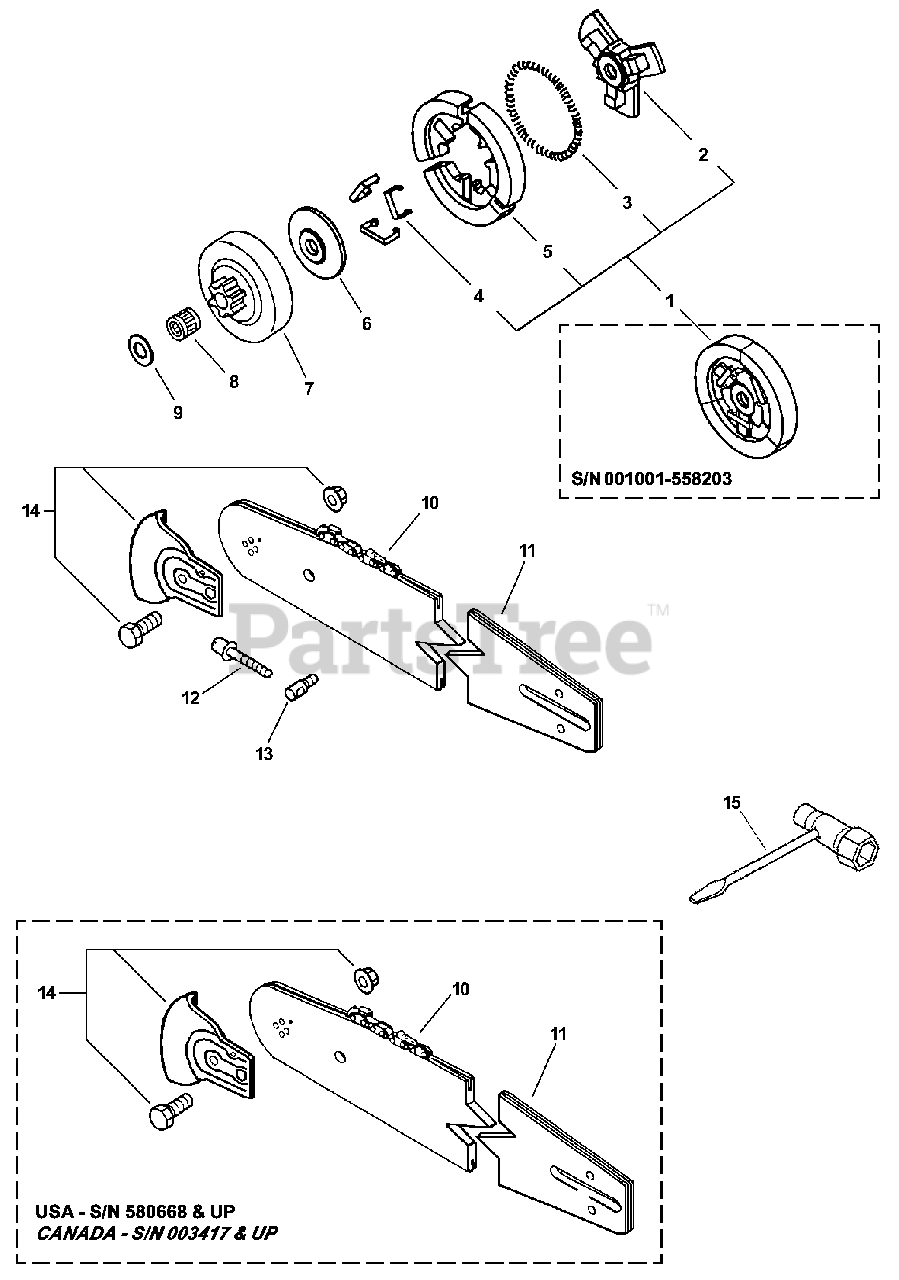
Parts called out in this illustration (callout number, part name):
1	CLUTCH ASSY
2	HUB, CLUTCH
3	SPRING, TORSION
4	SPRING, FLAT
5	SHOE, CLUTCH
5	SHOE SET, CLUTCH (3PCS)
6	PLATE, CLUTCH
7	DRUM, CLUTCH 3/8"
8	BEARING, NEEDLE 10×13×10
9	WASHER 10.2×24.5×1.2
10	SAWING CHAIN - 12" -- XTRAGUARD
10	SAW CHAIN 14" XTRAGUARD
10	SAW CHAIN 16"
11	GUIDE BAR, 12" DOUBLE-GUARD
11	GUIDE BAR, 14" DOUBLE-GUARD
11	GUIDE BAR, 16" DOUBLE-GUARD
11	GUIDE BAR, 12"
11	GUIDE BAR, 14"
11	GUIDE BAR, 16"
12	BOLT 5
13	TENSIONER, CHAIN
14	KICK GUARD KIT
15	T-WRENCH 10×19 MM
